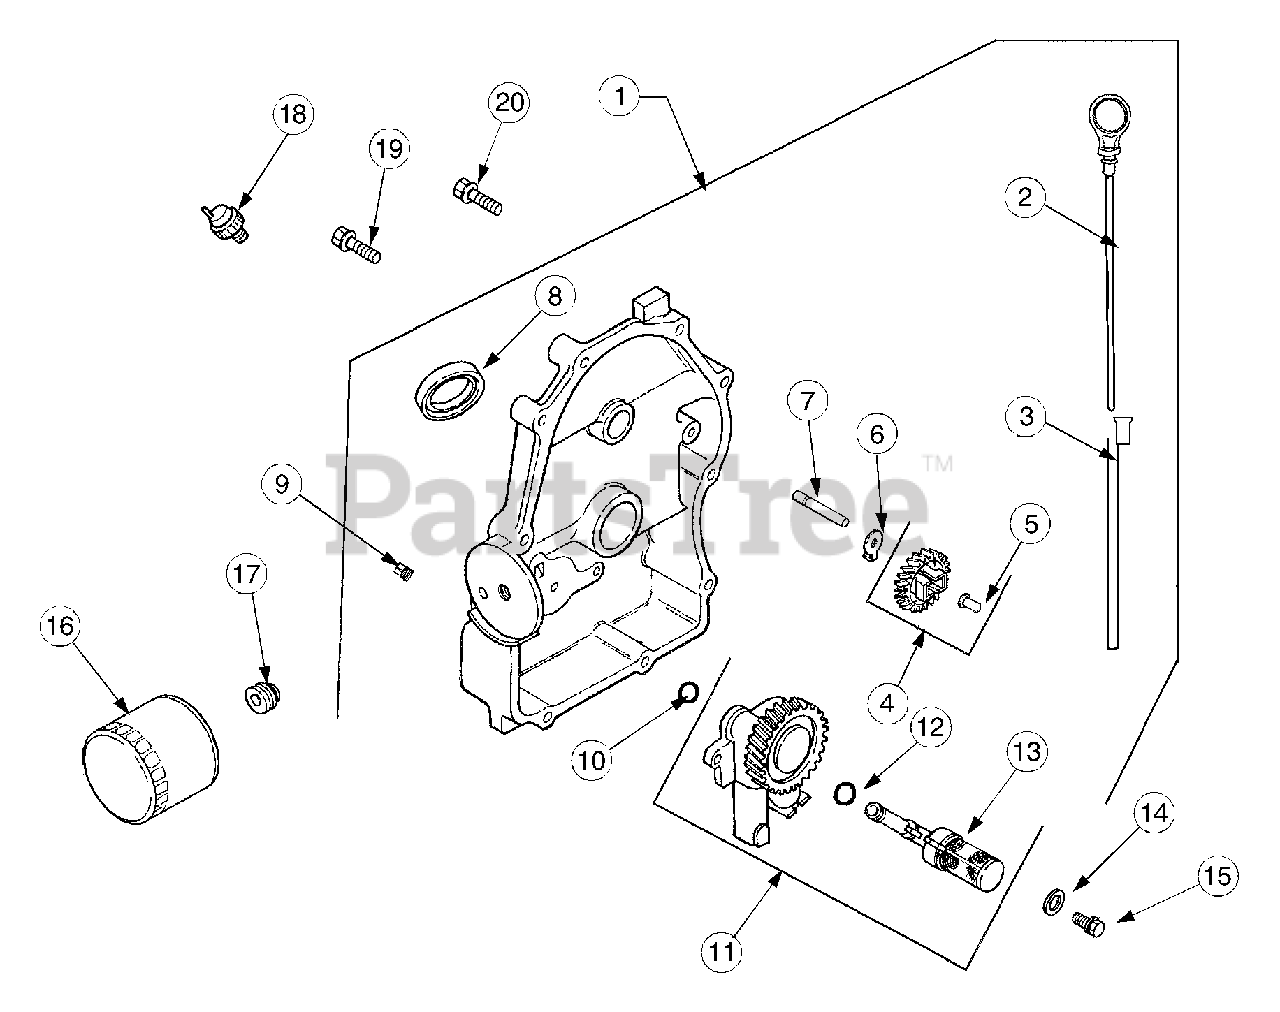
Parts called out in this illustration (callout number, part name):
1	Plate Assy, Closure
3	Tube, Dipstick
4	Kit, Governor Gear
5	Pin, Governor Regulating
7	Shaft, Governor Gear
8	Seal, Oil (PTO end)
9	Plug, Pipe 1/8
11	Oil Pump Assy
12	O-Ring, Oil Pick-up
13	Pick-up, Oil
14	Washer, Plain
15	Screw, Hex Flange, M6 x 1.0 x 25
16	Filter, Oil
17	Nipple, Oil Filter
18	Switch, Pressure
19	Screw, Hex Flange, M8 x 1.25 x 45
20	Screw, Hex Flange, M8 x 1.25 x 45
